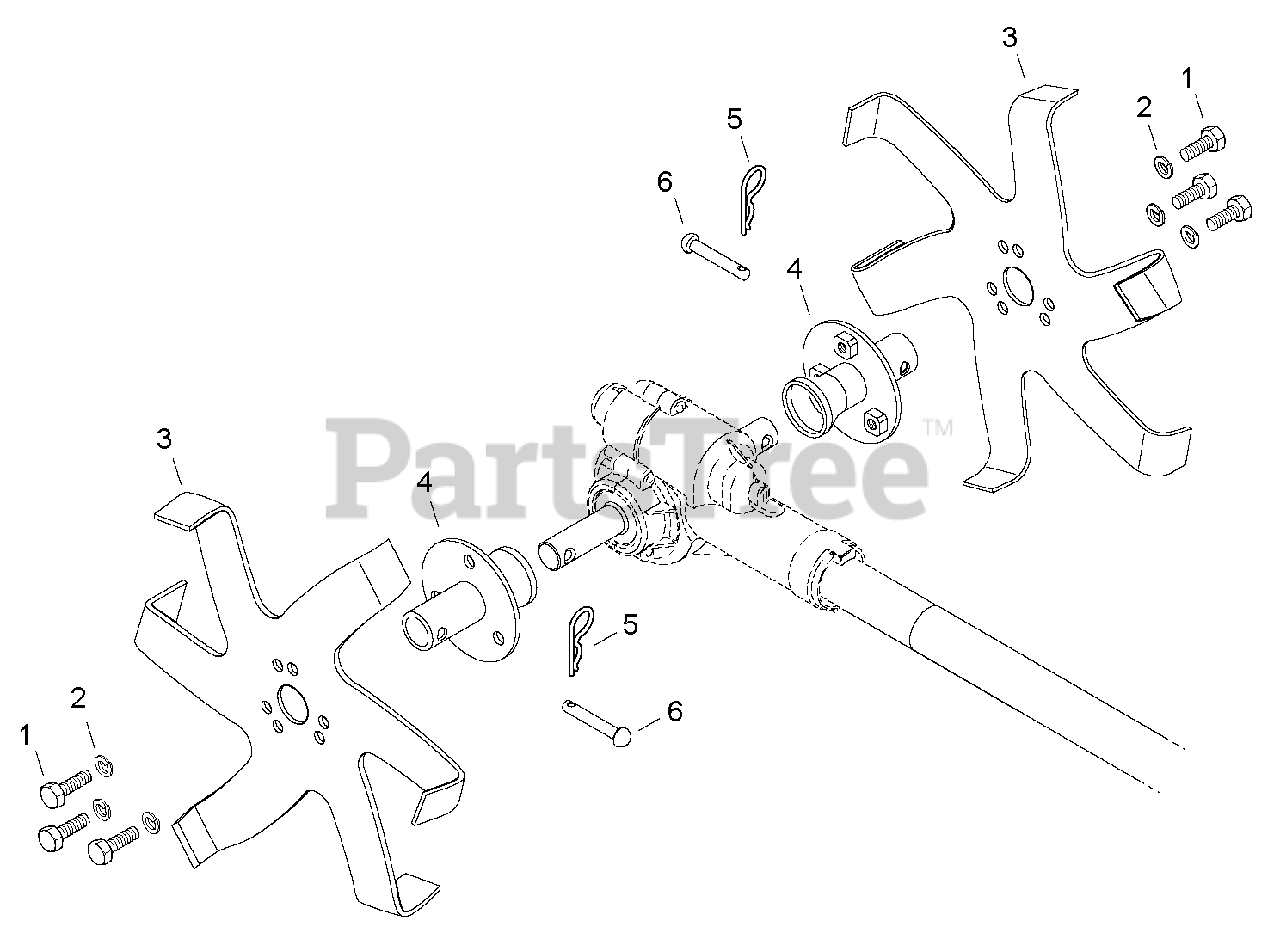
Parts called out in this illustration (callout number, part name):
1	BOLT 6×10
2	WASHER, SPRING 6
4	HUB, TINE
5	PIN, COTTER 5
6	PIN, CLEVIS
